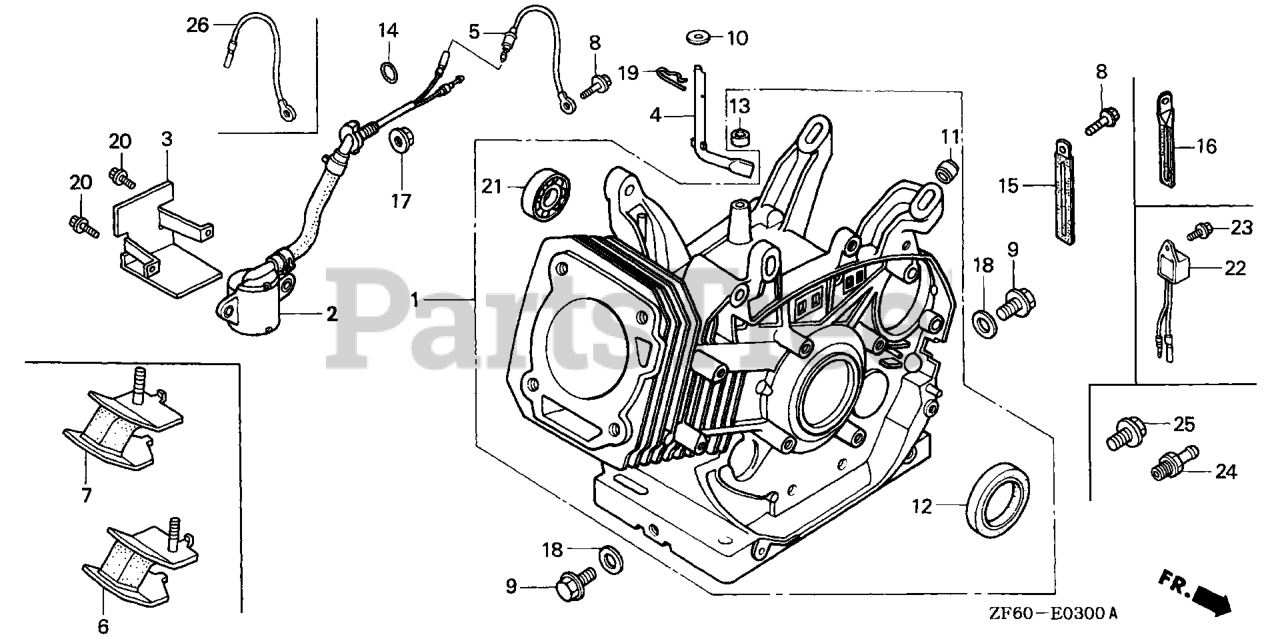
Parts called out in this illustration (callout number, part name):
1	CYLINDER ASSY. (SELF STARTER+ALERT)
2	SWITCH ASSY., OIL LEVEL
4	SHAFT, GOVERNOR ARM
5	SUB-HARNESS (NOT AVAILABLE)
8	BOLT, FLANGE (6X12) (CT200)
9	BOLT, DRAIN PLUG
10	WASHER (8.2X17X0.8)
12	OIL SEAL (35X52X8)
13	OIL SEAL (8X14X5)
14	O-RING (14MM) (ARAI) Use up to Engine SN 2949254.
17	NUT, FLANGE (10MM)
18	WASHER, DRAIN PLUG (12MM)
19	PIN, LOCK (8MM)
19	PIN, LOCK (10MM)
20	BOLT, FLANGE (6X12) Use up to Engine SN 1543277.
21	BEARING, RADIAL BALL (6202)
